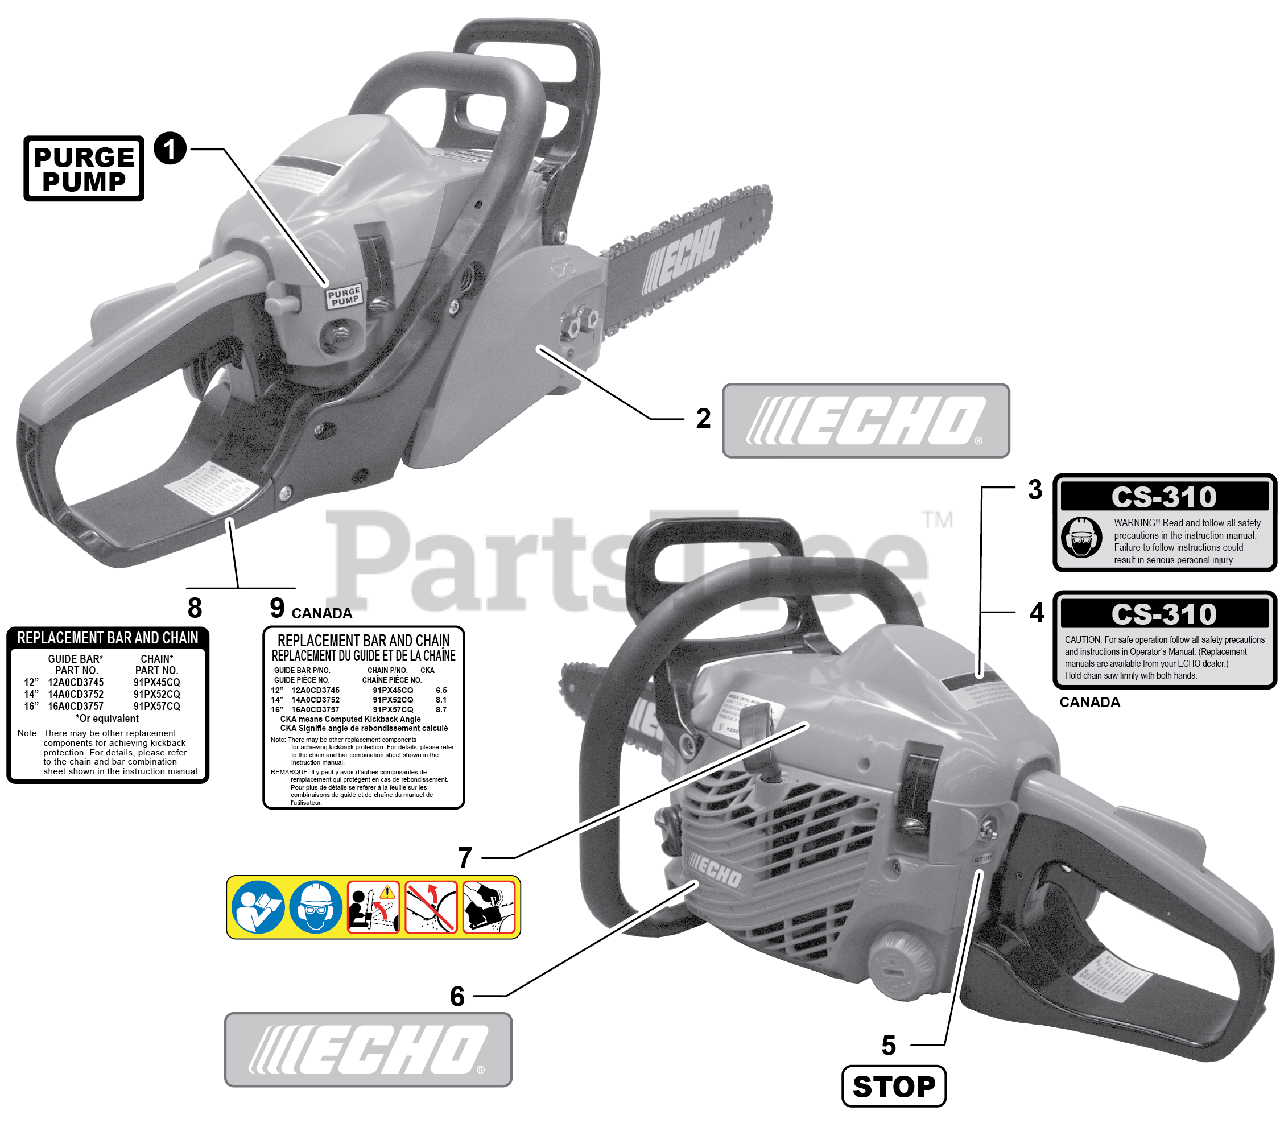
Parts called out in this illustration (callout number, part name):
1	LABEL, PURGE PUMP
2	LABEL, ECHO
3	LABEL, MODEL CS-310
4	LABEL, MODEL CS-310
5	LABEL, STOP
6	LABEL, ECHO
7	LABEL, CAUTION
8	LABEL, BAR & CHAIN
9	LABEL, BAR & CHAIN
